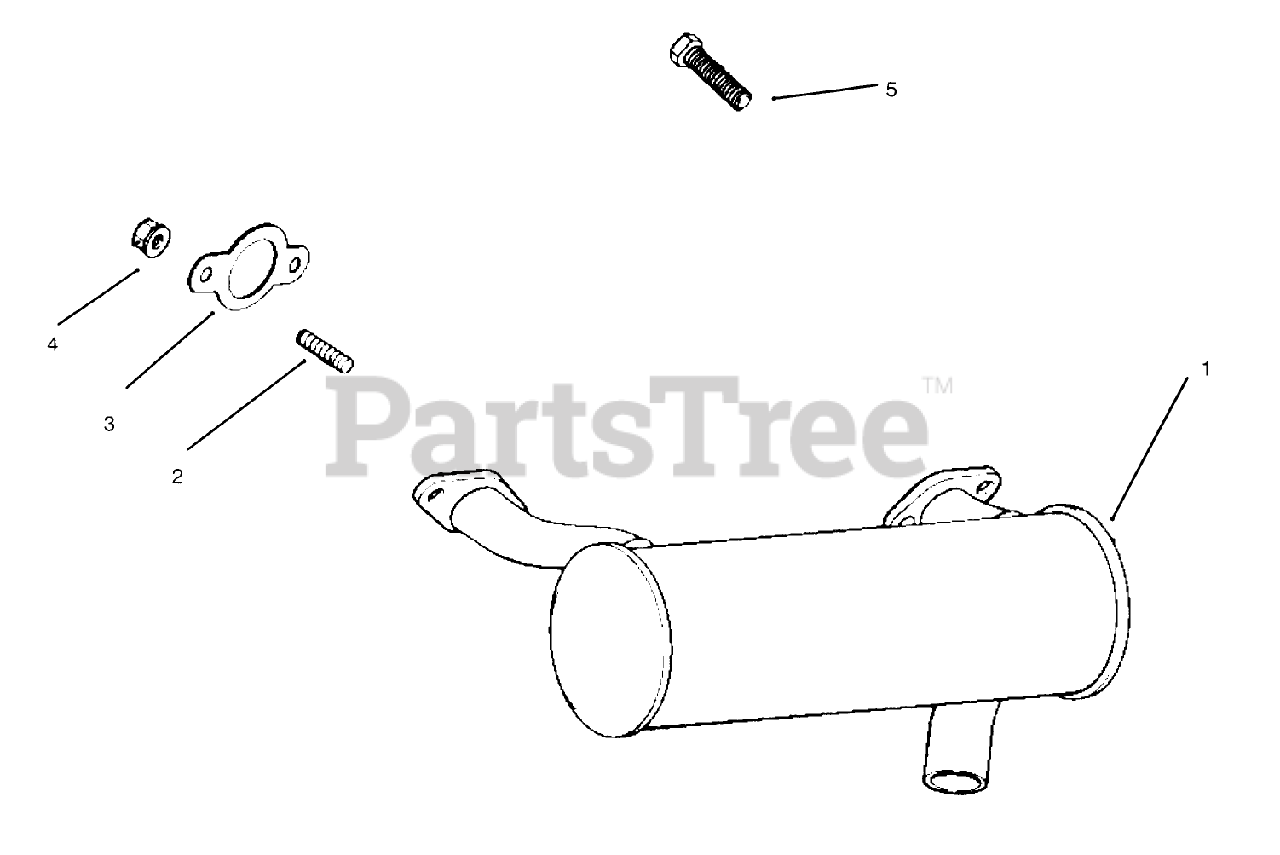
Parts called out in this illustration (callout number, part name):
1	Muffler
2	Stud
3	Gaskt-Exhaust
4	Nut
5	Screw, tank bracket - starter end
